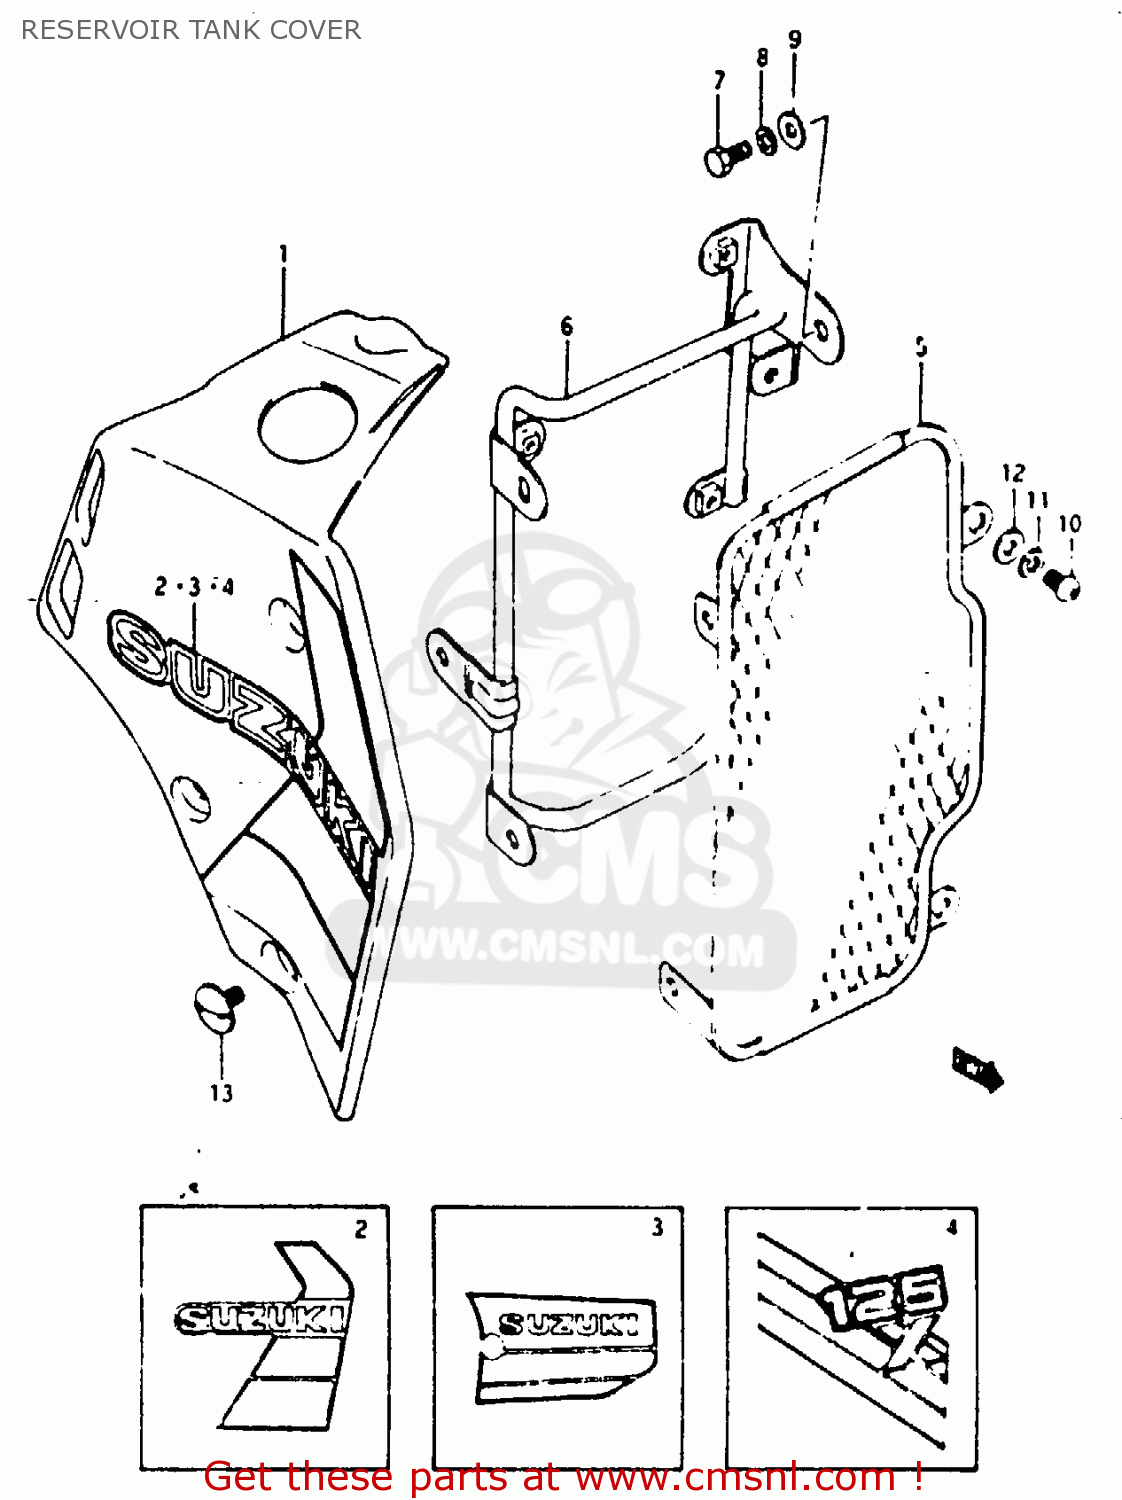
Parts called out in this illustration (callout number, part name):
1	COVER, RESERVOIR TANK (RED)
2	TAPE SET
3	TAPE SET
4	TAPE SET
5	GUARD, RESERVOIR TANK
6	STAY, RESERVOIR TANK COVER
7	BOLT
8	WASHER,LOCK
9	WASHER
10	SCREW
11	WASHER,LOCK
12	WASHER
13	SCREW(6X14)
